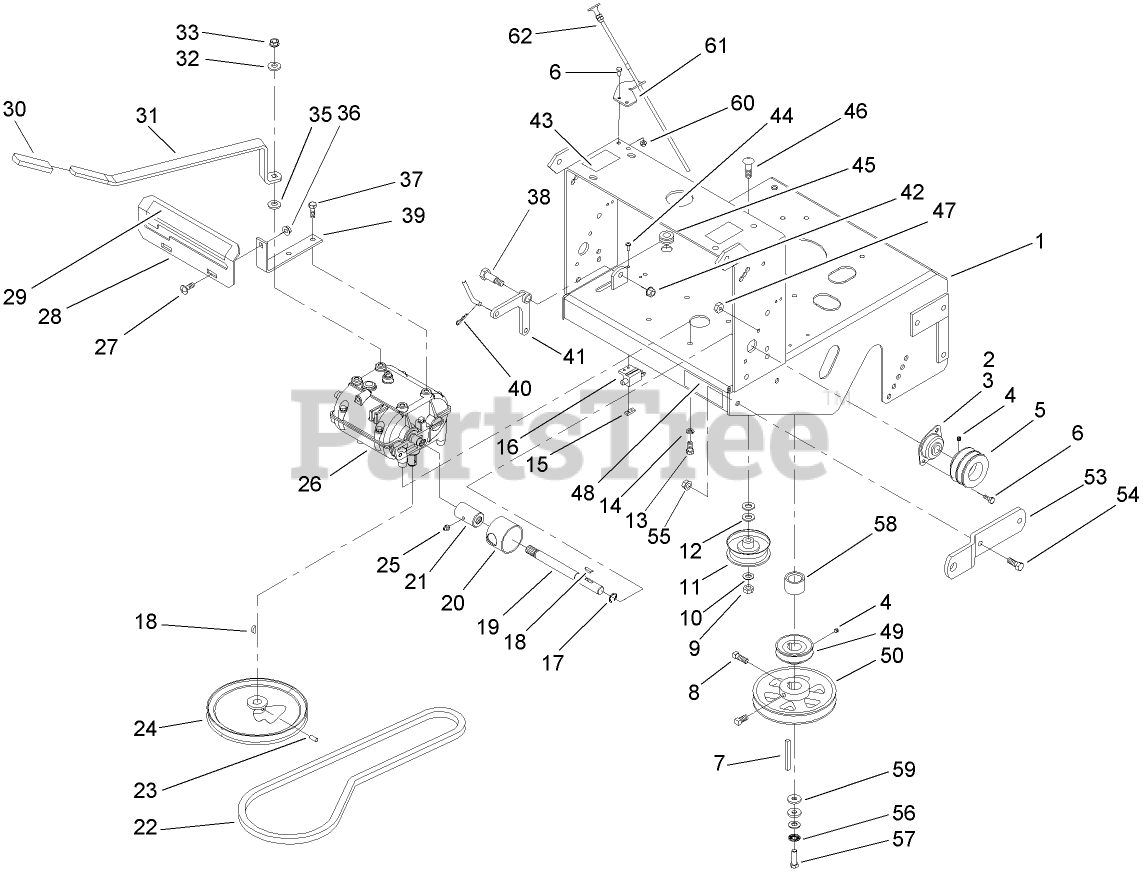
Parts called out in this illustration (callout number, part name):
1	FRAME-DECK, REAR
2	BEARING-SHAFT
3	FLANGE-OUTPUT
4	SCREW-SET
5	SHEAVE-TRANSMISSION
6	SCREW-HH
8	SCREW-SET, SQH
9	NUT-LOCK, NI
10	WASHER-FLAT
11	PULLEY-IDLER, FLAT
12	WASHER-FLAT
13	SCREW-HH
14	WASHER-LOCK
15	PLATE-TAPPED
16	SWITCH-CLOSED, NORMALLY
17	RING-RETAINING
18	KEY-WOODRUFF
19	SHAFT-TRANSMISSION
20	GUARD-COUPLER
21	COUPLER
22	V-BELT
23	SCREW-HSH
24	SHEAVE-TRANSMISSION
25	FITTING-GREASE
26	TRANSMISSION
27	BOLT-CARR
28	PLATE-SHIFT
29	DECAL-SPEED, GROUND
30	GRIP-LEVER
31	LEVER-SHIFT
32	WASHER-BELLEVILLE
33	NUT-LOCK
35	WASHER
36	NUT-HF
37	SCREW-HWH, THREAD CUT
38	BOLT-SHOULDER
39	BRACKET-PLATE, SHIFT
40	PIN-COTTER
41	BELLCRANK
42	NUT-HHF, WHIZ
43	DECAL-SHUT OFF, FUEL
44	SCREW-PPH
45	GROMMET
46	SCREW-CARR
47	NUT-LOCK, NI
48	DECAL-CAUTION
49	Sheave-Transmission
50	Sheave
53	HITCH-SULKY
54	SCREW-HH
55	NUT-HHF, WHIZ
56	WASHER-SPRING
57	SCREW-HH
58	SPACER-CLUTCH
59	WASHER
60	NUT-HF
61	Bracket-Cable, Choke
62	Cable-Choke
